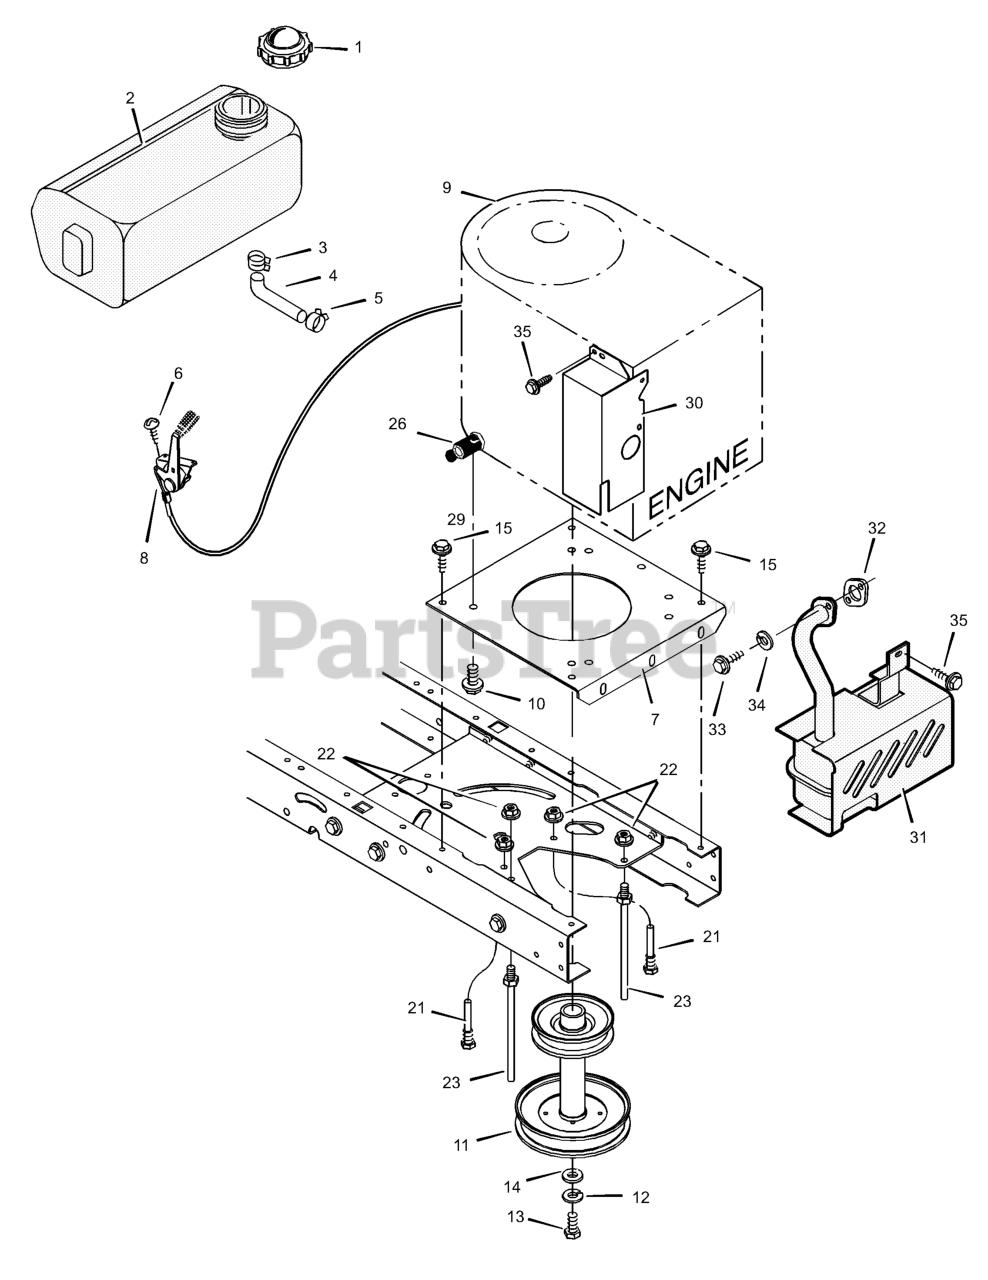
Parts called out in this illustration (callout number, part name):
1	Fuel Cap
2	Fuel Tank
3	Hose Clamp
4	Fuel Line (Must cut to length)
5	Hose Clamp
7	Plate, Engine
8	Throttle Control
9	Engine
10	Bolt, Engine Mount
11	STACK PULLEY ASSEMBLY
12	Lockwasher
13	Bolt, Hex
21	Guide, Belt
22	Nut, Flange
23	Guide, Belt
26	Oil Drain Valve
30	Shield, Heat
32	GASKET, Exhaust
34	Washer
